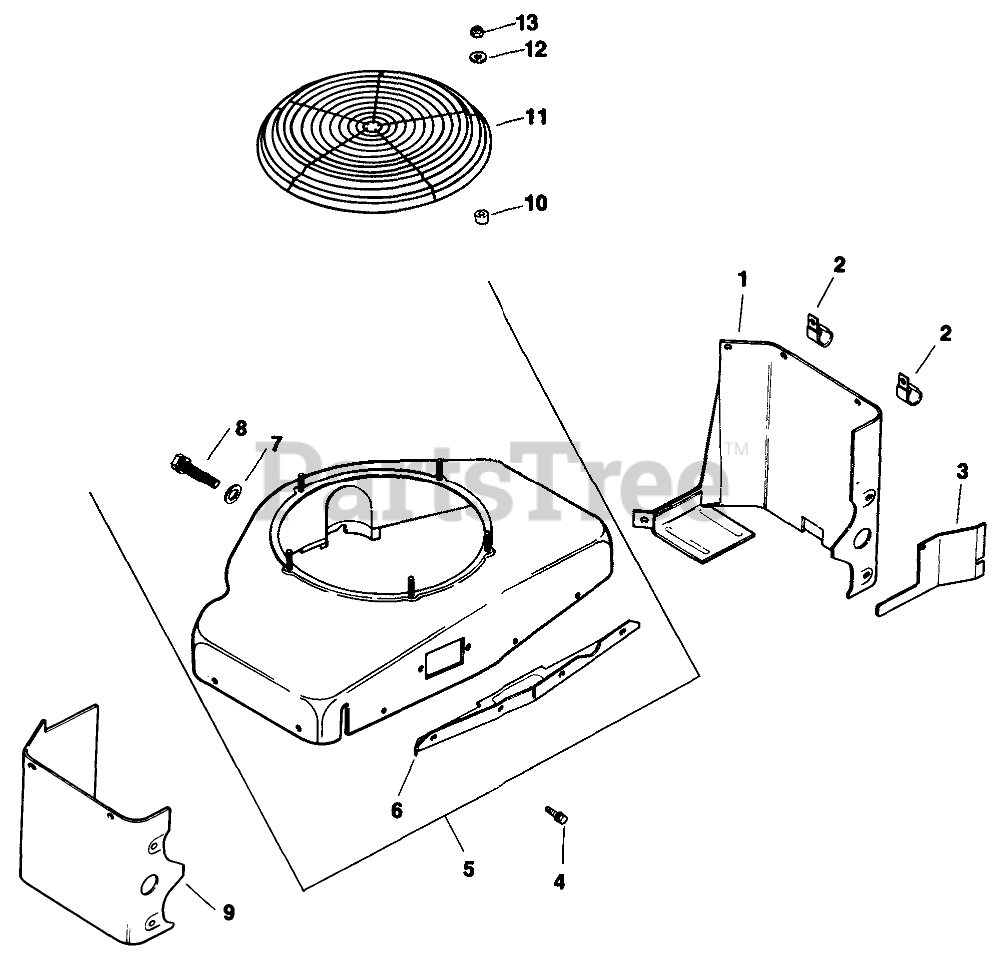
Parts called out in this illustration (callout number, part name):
1	Baffle-Cylinder Head
2	Clamp
3	Baffle-Cylinder Head
4	Screw
5	Kit-Blower Housing (Incl. Ref. #6-8)
6	Support-Upper Housing
8	Screw-H.C
9	Baffle-Cylinder Head
11	GuARd-Grass Screen
13	Locknut
